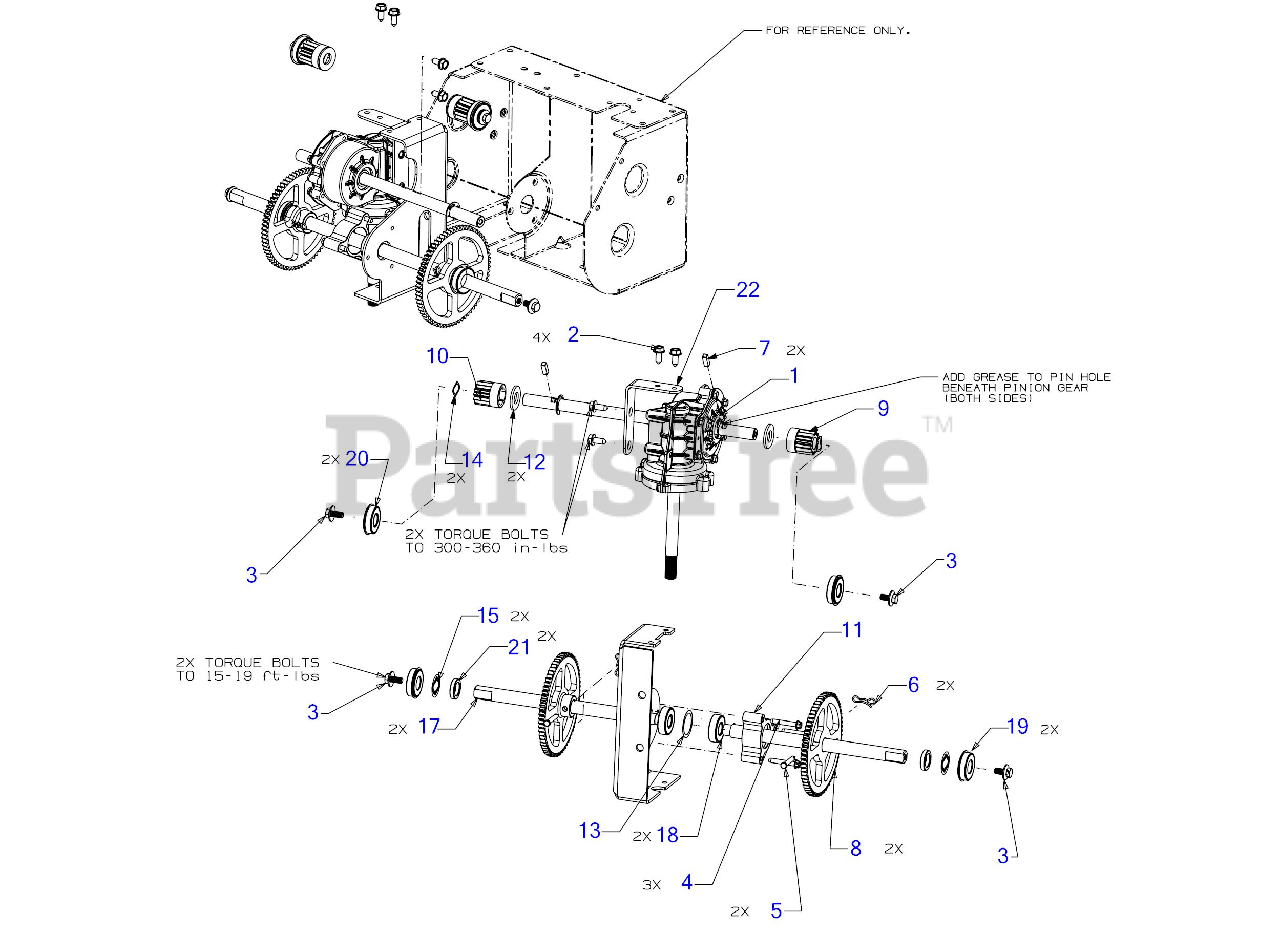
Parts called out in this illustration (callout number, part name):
1	TRANSMISSION ASSEMBLY
2	SCREW 5/16-18 x .750
3	SCREW 5/16-24 x .750 GR5
4	SCREW 1/4-20 X1.625
6	BOW TIE COTTER PIN 1/4-5/16
7	SQUARE KEY
9	SPUR GEAR 14T (LH)
10	SPUR GEAR 14T (RH)
11	BEARING CUP
12	INPUT SHAFT WASHER
13	SHIM WASHER
14	WAVE WASHER
18	BALL BEARING
19	BALL BEARING
20	BALL BEARING
22	ANTI-ROTATION BRACKET
